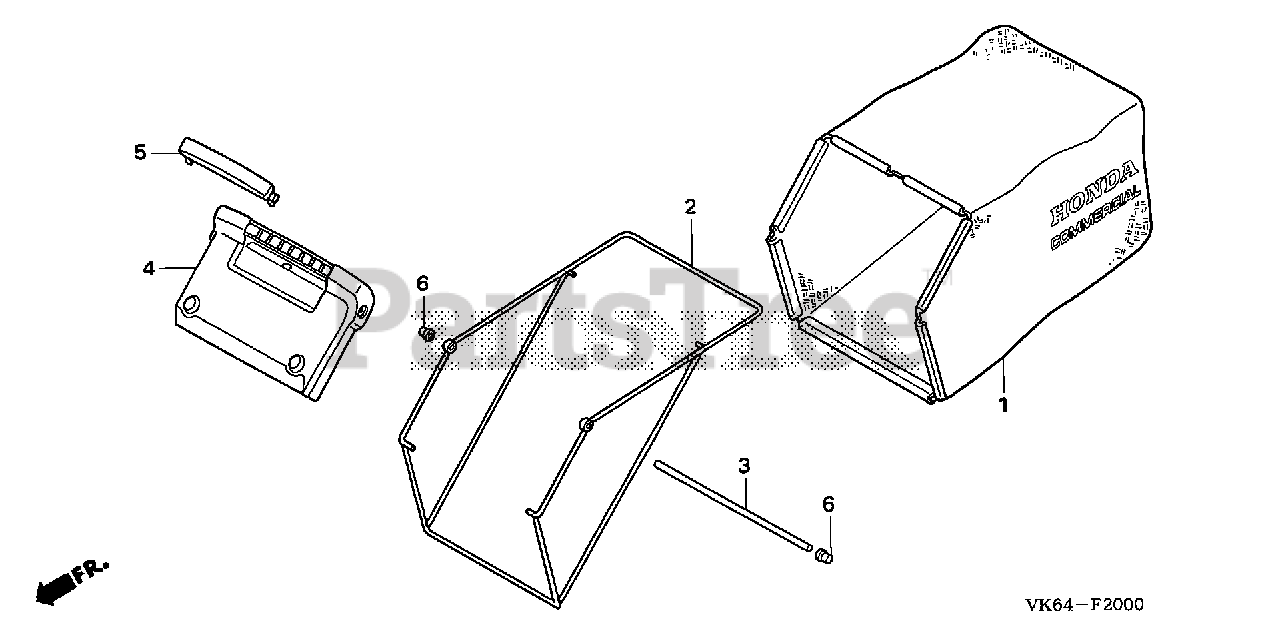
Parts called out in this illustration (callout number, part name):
1	FABRIC, GRASS BAG
2	FRAME, BAG (LOWER)
3	JOINT, GRASS BAG
4	CATCHER, GRASS (UPPER)
5	COVER, GRASS CATCHER GRIP
6	NUT, PUSH (8MM)
